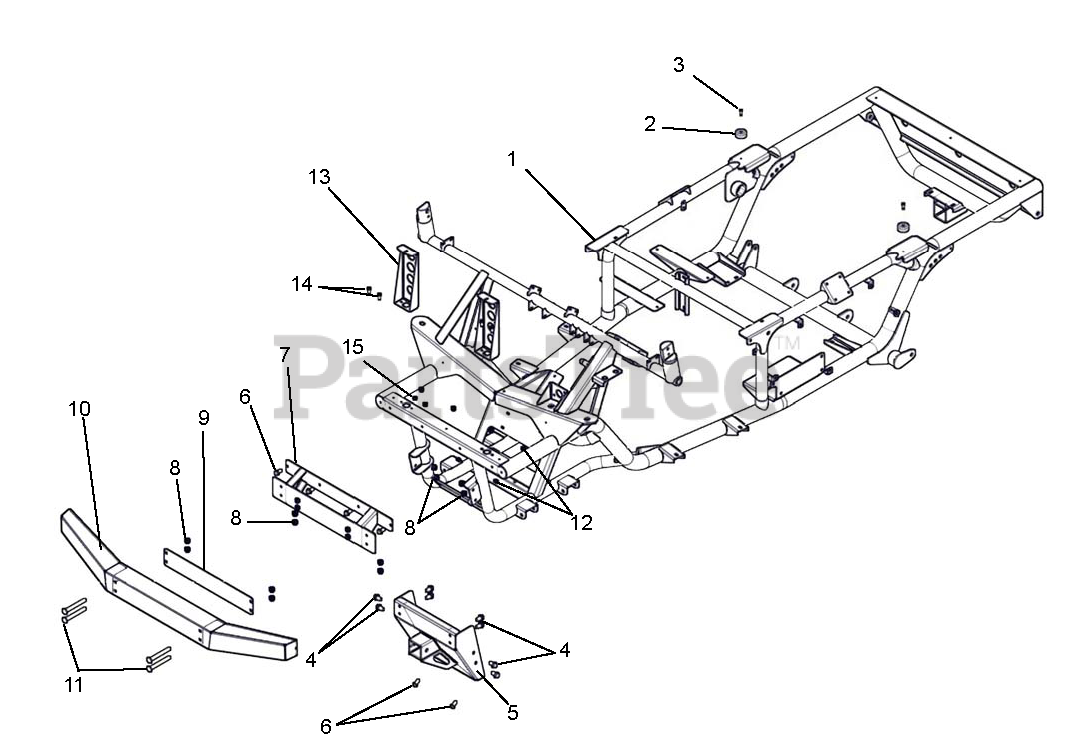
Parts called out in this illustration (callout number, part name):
1	WLDT-MAINFRAME
2	BUMPER, RUBBER .625 X 1.50 DIA
3	RIVET, 3/16 X .500 POP ST
4	HFSS 3/8-16X3/4 LG
5	WLDT, RECEIVER, FRONT
6	BLT-SERHFWH .312-18X.75 YWZC
7	WLDT, MNT,BUMPER
8	@NUT-SPNLK-FLG .375-16 YWZC
9	PLATE,BACK,BUMPER
10	WLDT, BUMPER
11	BLT-RDHDSQNK .38-16X4.00 G5 Y
12	@NUT-SPNLK-FLG .312-18 YWZC
13	HOOD MOUNT BRACKET
14	@BLT-HEX .25-20X.75 GR5 YWZC
15	@NUT-SPNLK-FLG .25-20 YWZC
16	DECAL, ARIENS JEWEL
